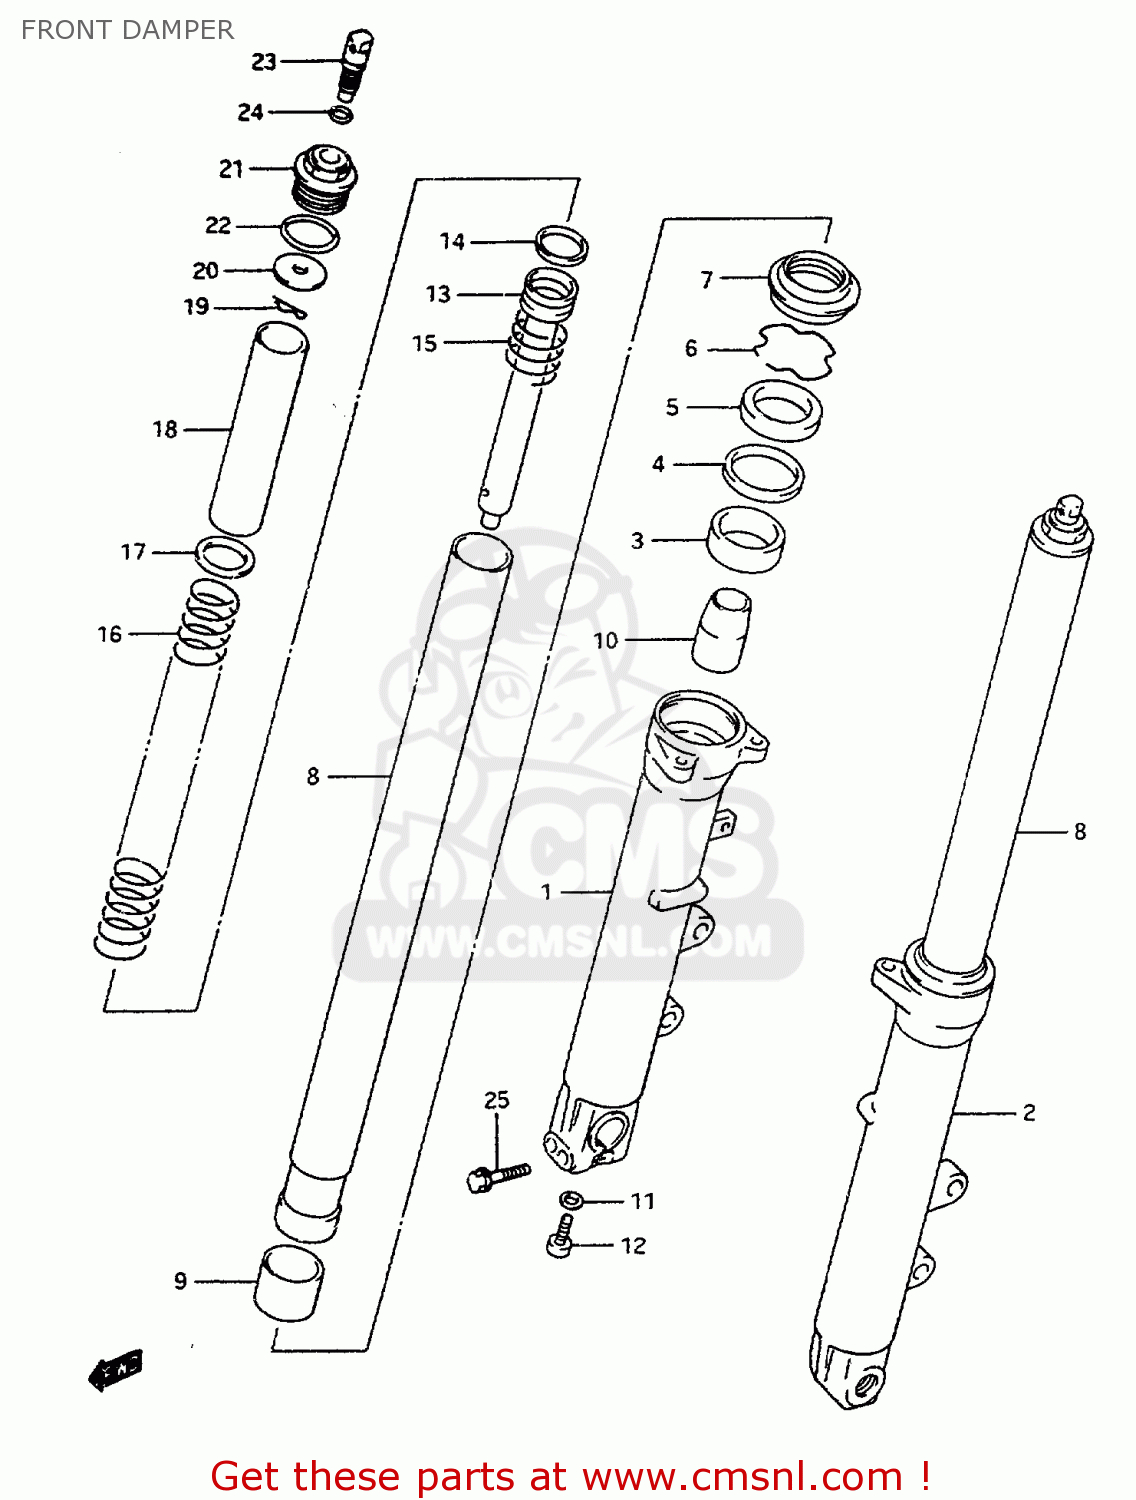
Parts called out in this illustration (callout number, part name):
00000	DAMPER ASSEMBLY,LEFT
1	TUBE,OUTER,RIGHT
2	TUBE,OUTER,L
3	BUSH,GUIDE
4	SPACER,SEAL
5	SEAL,OIL
6	CIRCLIP,FORK OIL SEAL
7	SEAL,DUST
8	TUBE,INNER
9	BUSH,SLIDE
10	PIECE,OIL LOCK
11	GASKET (NAS)
12	BOLT(8X27)
13	CYLINDER
14	RING,PISTON
15	SPRING,REBOUND
16	SPRING,MAIN
17	JOINT,SPRING
18	COLLAR,SPRING
19	PIN,SEAT SPRING
20	SEAT,SPRING
21	BOLT,FORK
22	O RING
23	BOLT,SPRING ADJUSTER
24	O RING(D:1.9,ID:8.6)
25	BOLT
